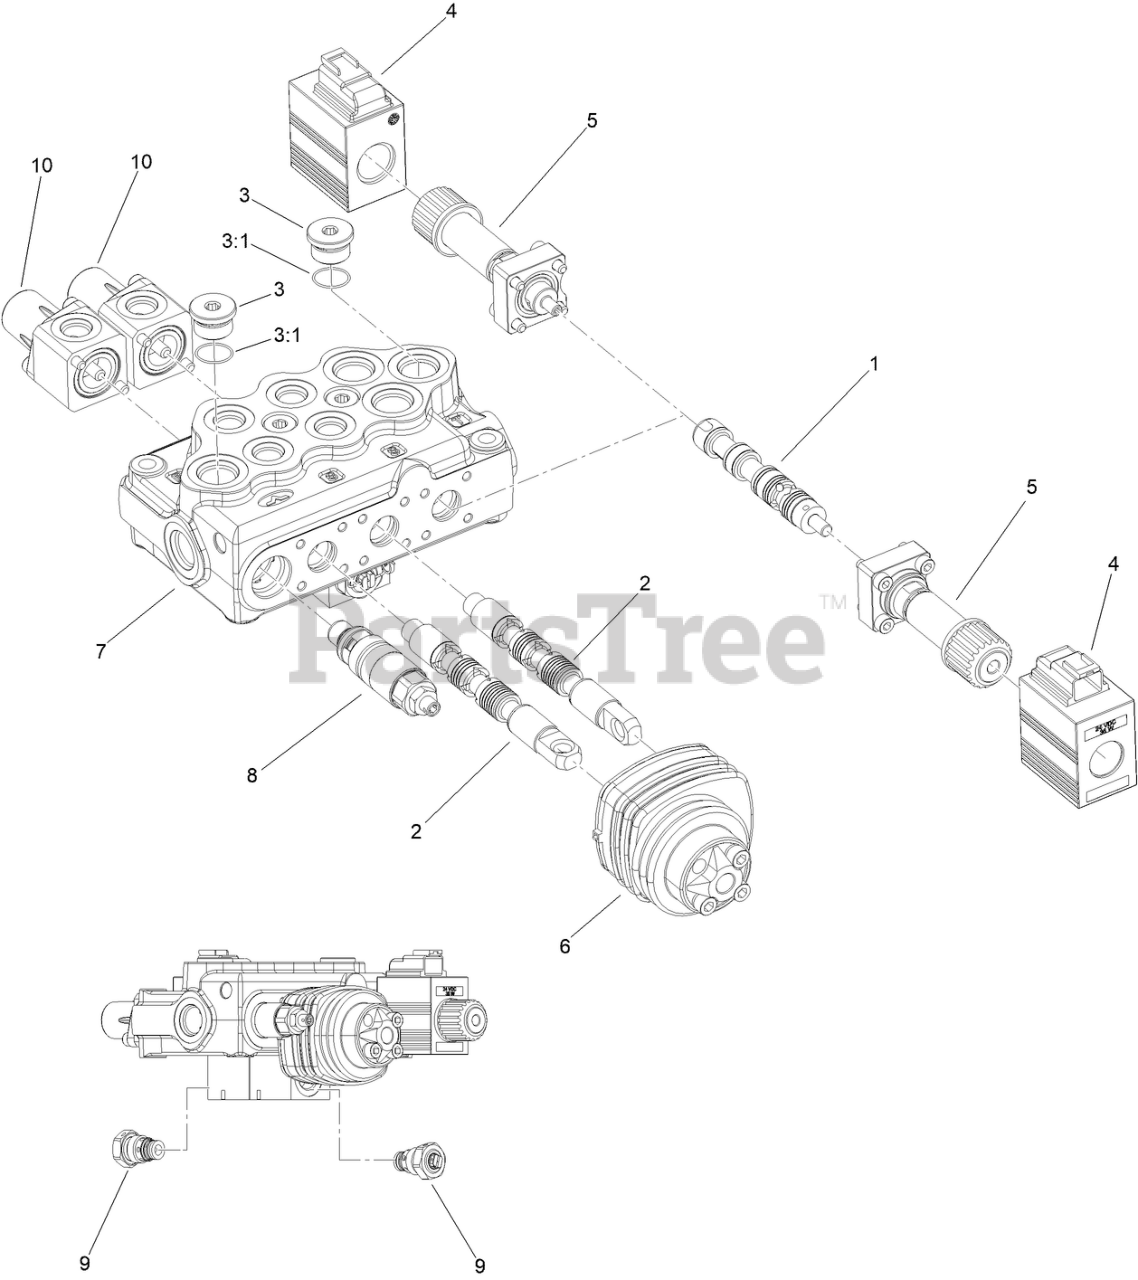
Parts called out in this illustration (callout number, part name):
1	VALVE-SPOOL
2	VALVE-SPOOL
3	PLUG-HEX
3:1	O-RING
5	KIT - CONTROLLER
6	KIT - JOYSTICK
7	KIT - BODY
8	KIT - VALVE
9	KIT - VALVE [100 - 155 BAR]
10	SWITCH SPRING RETURN KIT
